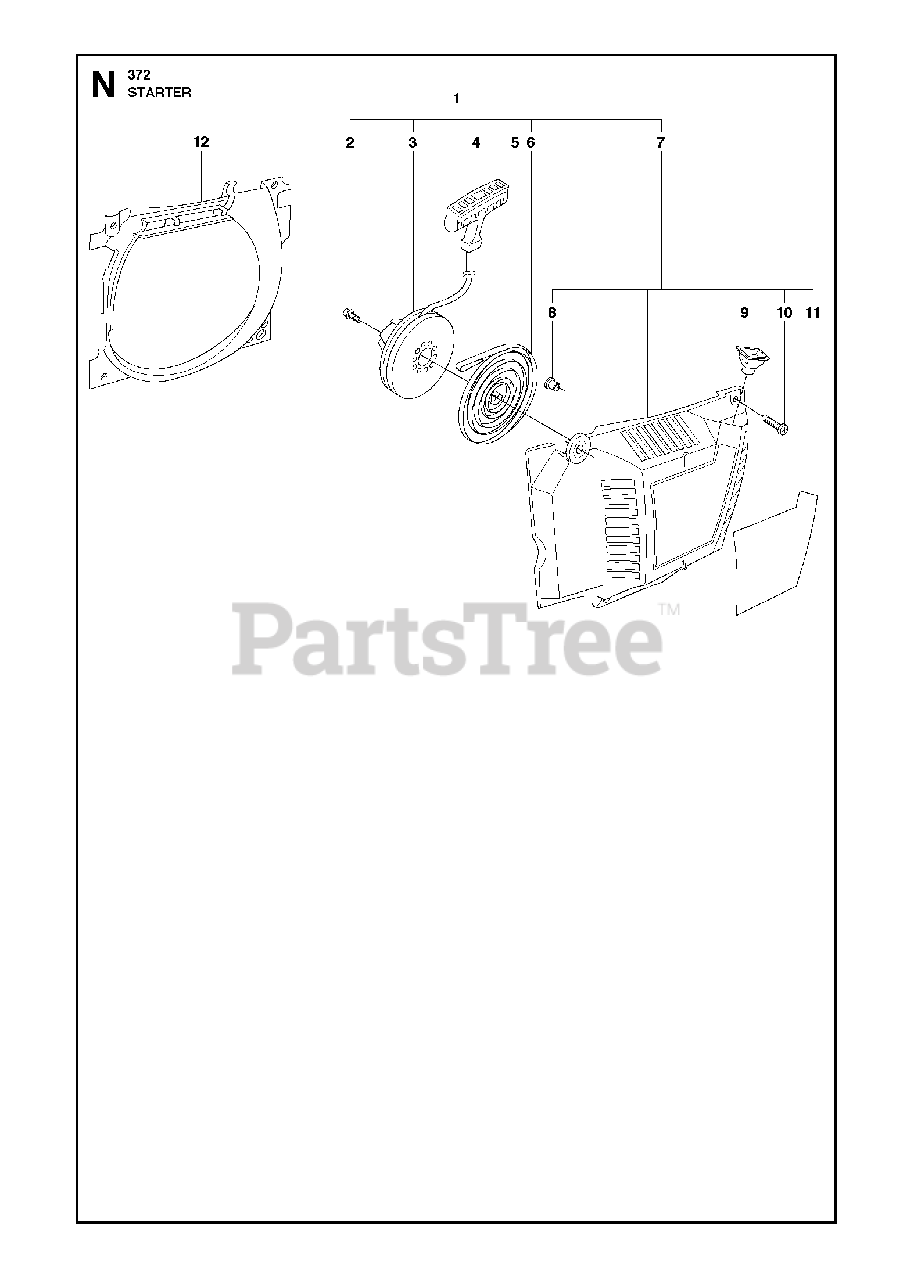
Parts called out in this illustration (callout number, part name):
1	STARTER ASSY
2	SCREW
3	STARTER PULLEY
4	STARTER HANDLE
5	STARTER CORD
6	SPRING
7	STARTER HOUSING
8	BUSHING
9	SLEEVE
10	SCREW
11	372XP DECAL
11	372XPG DECAL
12	AIR CONDUCTOR
